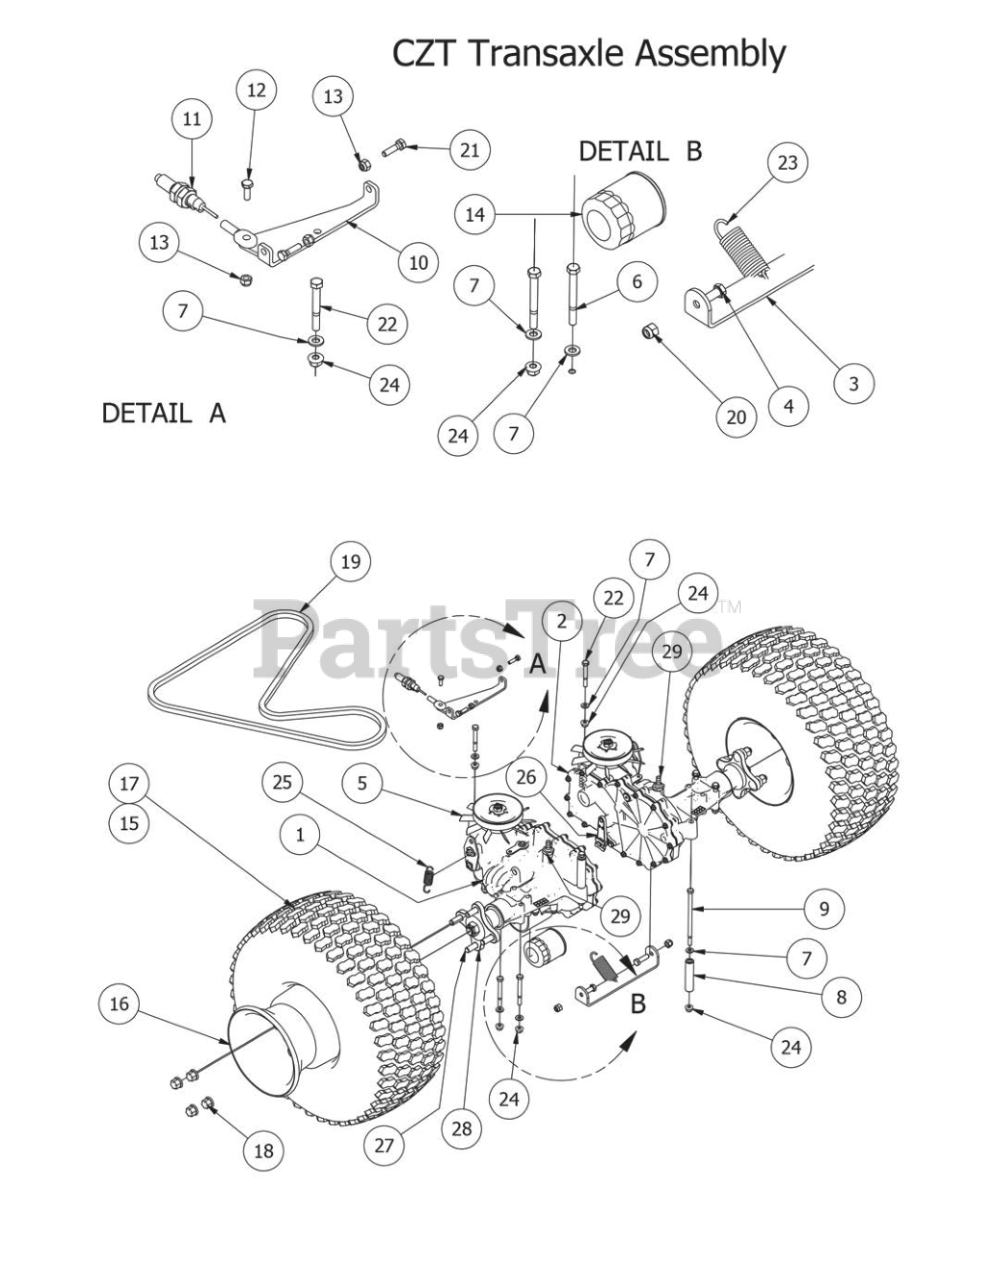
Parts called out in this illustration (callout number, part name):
1	3400 IZT for CZT -Left
2	3400 IZT for CZT - Right
3	Crossover Bar for ZT
4	3/8" x2" Hex Bolt
5	Fan/Pulley kit For CZT
6	5/16" x 3" Hex Bolt
7	5/16" Flat Washer
8	3 1/4" Spacer
9	5/16" x 6" Bolt
10	ZT Crossover Brake Bracket
11	Brake Cable-Stand on
12	1/4" x 3/4" Hex Bolt
13	1/4" Nylock Nut
14	Transaxle Hydro Filter
15	Tire 23 X 10.50 -12 Assembly W/Negative Offset Wheel
16	12 Orange Wheel
17	23 x 10.50 Tire only
18	Acorn Lug Nut
20	3/8 Nylock Nut
21	1/4-20 x 1 GR 5 hex bolt zinc
22	5/16" x 2 1/2" Bolt
24	5/16" Nylon Flange Nut
25	Transaxle Spring
26	Transaxle Brake Lever
27	Transaxle Wheel Studs
28	ZT Transaxle Hub
29	45 degree fitting
